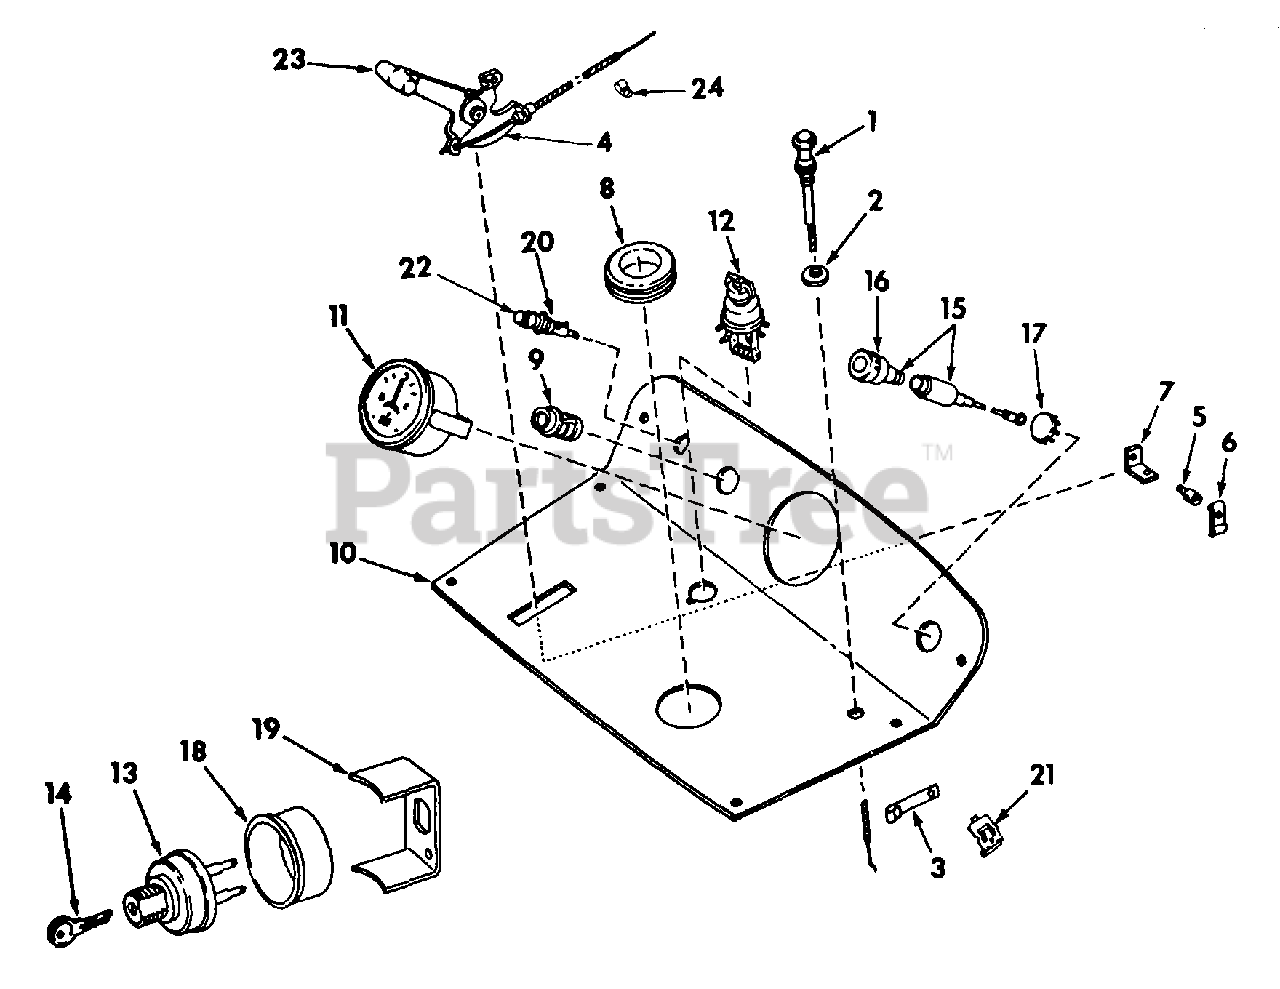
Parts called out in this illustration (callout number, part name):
1	CABLE ASSY, CHOKE LEVER
2	WASHER, BEZEL CHOKE
3	CLIP, CHOKE CABLE
4	LEVER, THROTTLE CABLE - LESS KNOB
5	PIN, GOVERNOR CONTROL SWIVEL
6	CLAMP, THROTTLE CONTROL
7	BRACKET ASSY, THROTTLE CONTROL
8	GROMMET, INSTRUMENT PANEL
9	SOCKET ASSY, TELLITE
10	PANEL, INSTRUMENT
11	INDICATOR ASSY, CHARGE
12	SWITCH ASSY, LIGHTING
13	SWITCH ASSY, BATTERY IGNITION KEY
14	KEY, IGNITION SWITCH
15	CIGARETTE LIGHTER PARTS ACCESSORY
16	UNIT, POP OUT
17	PLUG, 29/32 BUTTON CIGARETTE LIGHTER OPENING HOLE
18	SOCKET, IGNITION SWITCH
19	RETAINER, IGNITION SWITCH
20	HOUSING ASSY, FUSE
21	CLIP, SPEED
22	KNOB, FUSE HOLDER
23	KNOB, THROTTLE CONTROL CABLE LEVER
24	CLIP, THROTTLE CABLE
